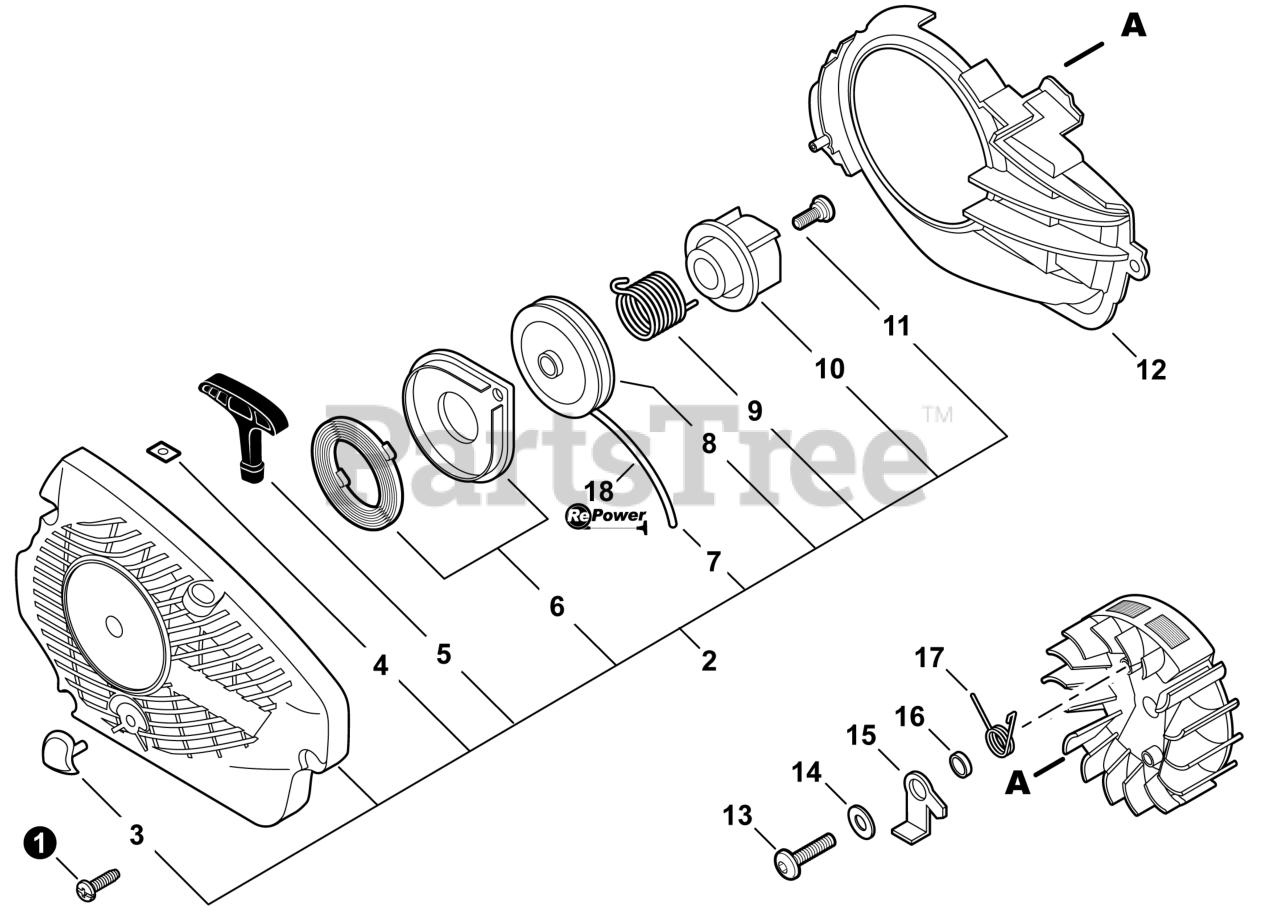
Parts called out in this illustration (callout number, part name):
1	SCREW 4×16
2	STARTER ASSY, RECOIL
4	RETAINER, ROPE
5	GRIP, STARTER
6	SPRING KIT, RECOIL
7	ROPE, STARTER
8	REEL, ROPE
9	SPRING, TORSION
10	PAWL CATCHER
11	SCREW 5
12	COVER, FAN
13	BOLT 5×14
14	WASHER 5.5×12×0.8
16	SPACER 5.2×8×2.1
17	SPRING, TORSION
18	BULK STARTER ROPE - Ø 3.5 MM×61 M
